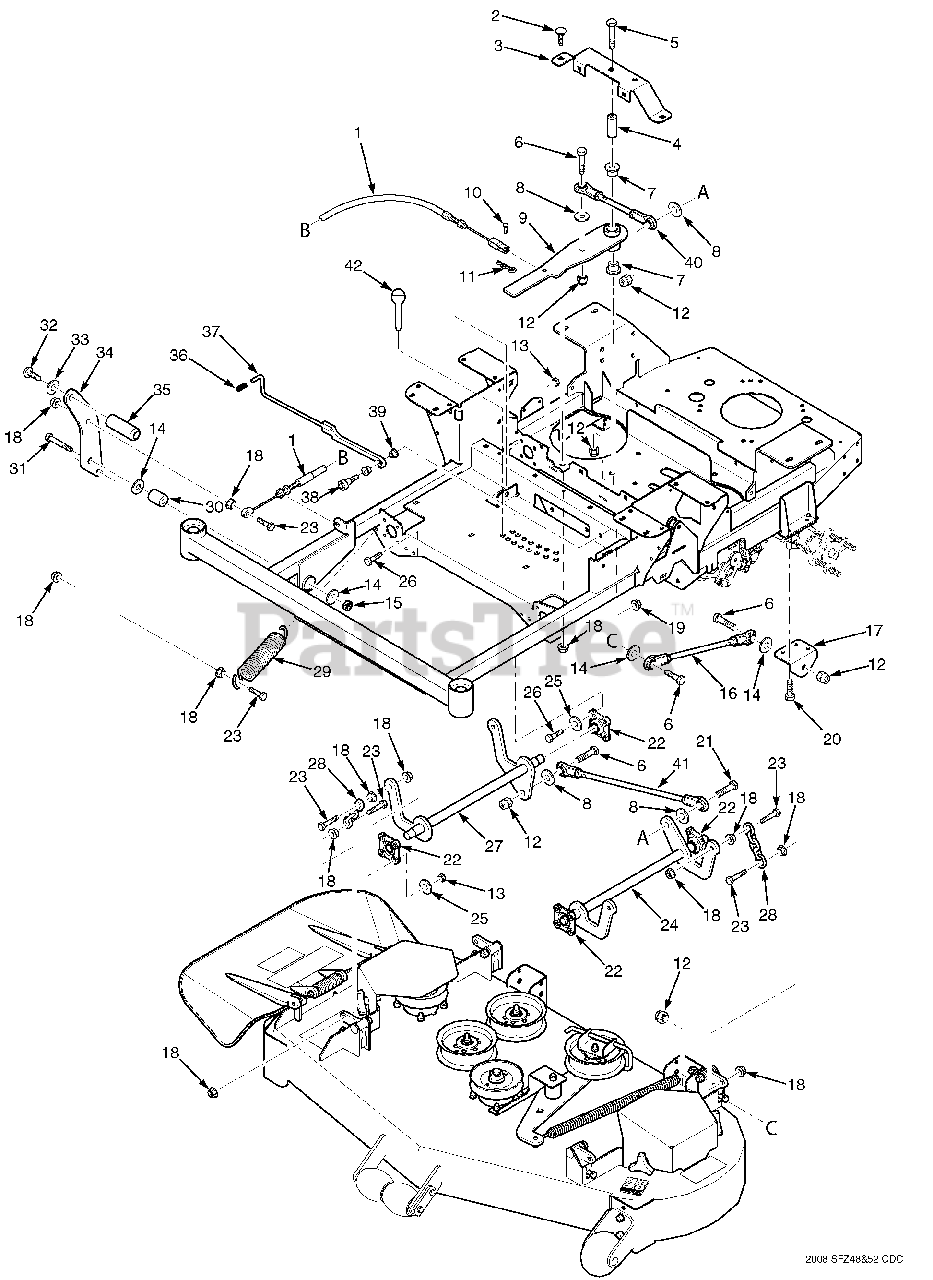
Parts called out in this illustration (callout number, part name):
1	Cable, Deck Lift
2	Bolt, Carriage 3/8-16 x 3/4"
3	Support, Idler Arm
4	Spacer, Deck Lift Pivot
5	Bolt, Hex Head 1/2-13 x 3-3/4"
6	Bolt, Hex Head 1/2-13 x 1-3/4"
7	Bearing
8	Flatwasher, 1/2-.531 x 1.06 x .095
9	Deck Lift Bellcrank Assembly
10	Clevis Pin, 5/16 x 3/4"
11	Hair Pin, .094 x 1.62"
12	Nut, Elastic Stop 1/2-13
13	Nut, Elastic Stop 5/16-18
14	Flatwasher, 1/2-.562 x 1.375 x .109
15	Nut, Center Lock 1/2-13
16	Linkage, Push Arm
17	Bracket, Push Arm Link
18	Nut, Serrated Flange 3/8-16
19	Nut, Elastic Stop 3/8-16
20	Bolt, Hex Head 5/16-18 x 3"
21	Bolt, Hex Head 1/2-13 x 2-1/2"
22	Bearing, Deck Lift
23	Bolt, Hex Head 3/8-16 x 1-1/2"
24	Weldment, Deck Lift LH
25	Flatwasher, 1/4-.312 x .750 x .065
26	Bolt, Hex Head 5/16-18 x 1"
27	Weldment, Deck Lift RH
28	Chain, Deck lift
29	Spring, Deck Lift
30	Sleeve, Deck Lift Pivot
31	Bolt, Hex Head 1/2-13 x 3"
32	Bolt, Head Socket 5/8-11 x 1-1/2"
33	Lockwasher, 5/8 Spring
34	Pedal, Foot Bracket
35	Foot Pedal
36	Grip, Deck Latch
37	Weldment, Deck Latch
38	Bolt, Shoulder 1/2 x 1/2
39	Bearing
40	Linkage Assembly, Deck Lift
41	Linkage Assembly, Deck Lift
42	Pin, Height Adjuster
